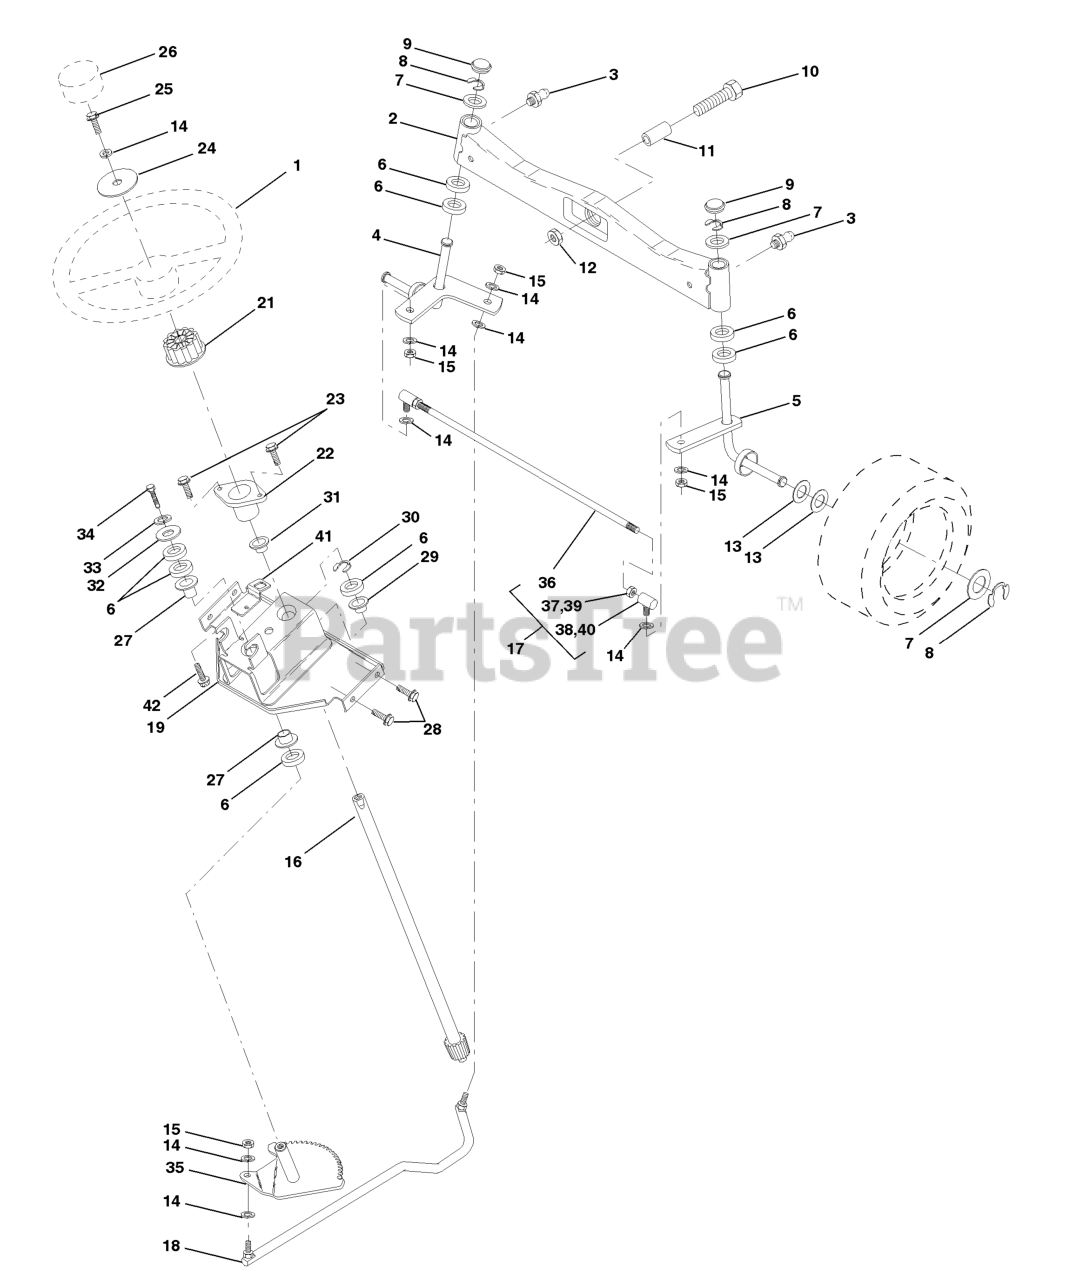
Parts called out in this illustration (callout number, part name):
1	STEERING WHEEL
2	FRONT AXLE ASSY
3	ZERK M
4	SPINDLE ASSY LH
5	SPINDLE ASM RH
6	THRUST WASHER
9	CAP.SPINDLE.BLACK
10	Bolt, Fin Hex 5/8-11 x 2-3/4
11	TUBE, PIVOT AXLE
12	NUT-LOC,FLANGE LT
14	WASHER, LOCK 3/8
15	GRIPCO NUT
16	SHAFT ASM, STEERING
17	ROD ASSY/TIE BALL
18	DRAGLINK-BALL JOINT SOLID
19	SUPPORT ASM., STEERING VGT
21	ADAPTER LT
22	BUSHING, STRG. BLK
23	SCREW.TT.#10-32X.5.3/8.FLANGE
24	WASHER T
25	BOLT
26	INSERT,STR WHEEL
27	BRNG T
28	SCREW
29	BEARING-FLANGE GT
30	Ring, Klip Truarc #5304-75
31	BUSHING.NYLINER.
33	WASHER.LOCK.HVY.HLCL.SPR.5/16
34	BOLT
35	GEAR.ASM.SECTOR.
36	TIE ROD
38	JOINT
41	BRACKET INTERLOCK
42	Screw Thdrol 5/16-18 x 1/2 Tyt.
